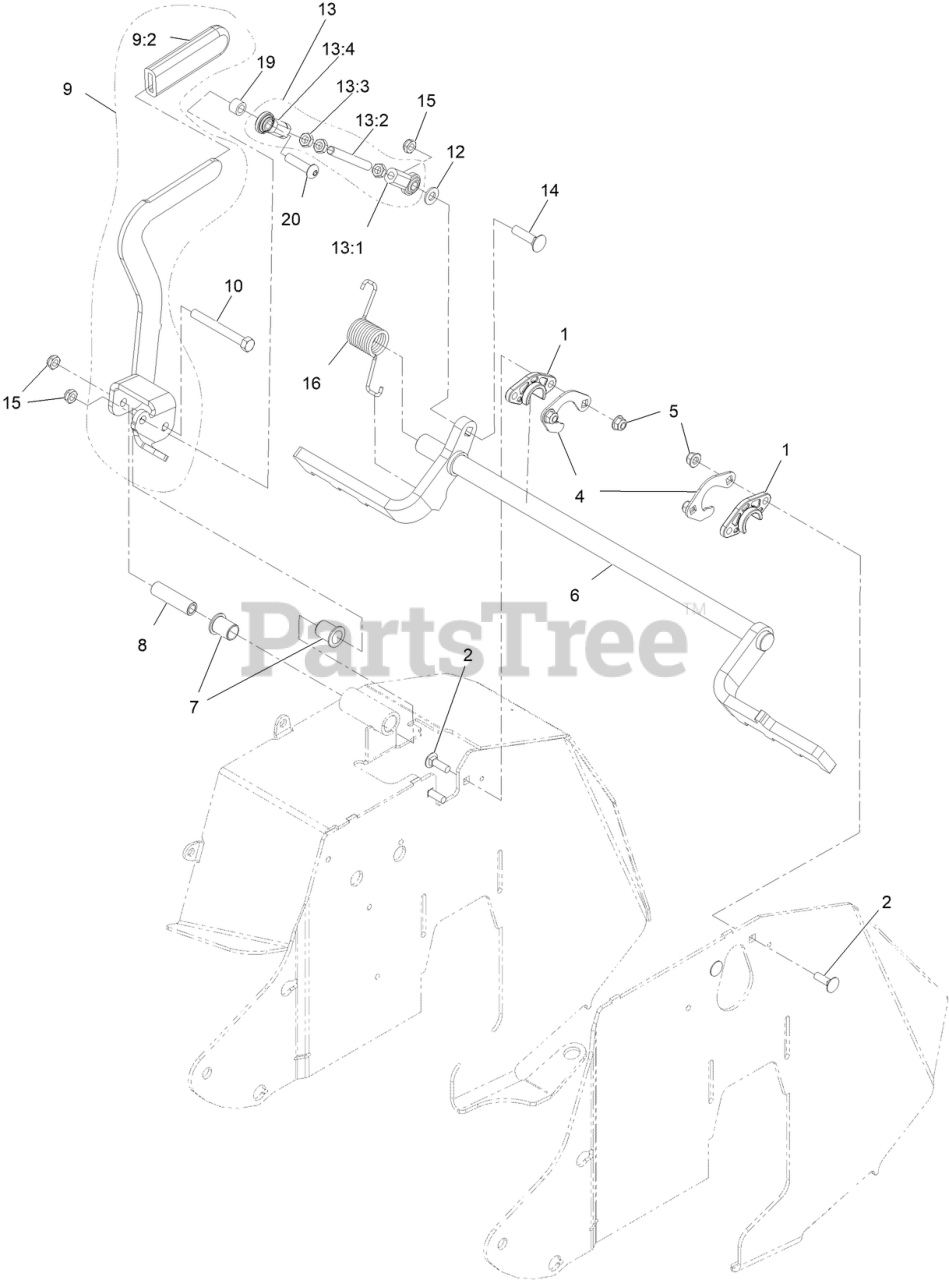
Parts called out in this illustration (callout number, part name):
1	BUSHING-FLANGE
2	BOLT-CARR
4	SUPPORT, BEARING
5	NUT-HF, NI
6	WLD-BRAKE SHAFT 32/36
7	BUSHING-FLANGE
8	SPACER, BRAKE PIVOT
9	ASM, LEVER W/ GRIP
9:2	GRIP-LEVER
10	SCREW-HH
12	WASHER-FLAT
13	ASM, BRAKE LINK
13:1	JOINT-BALL, END
13:2	LINKAGE, BRAKE
13:3	NUT-HJ
13:4	JOINT-BALL END, LH
14	SCREW-CARR
16	SPRING-TORSION
19	SPACER
20	SCREW-HSBH
